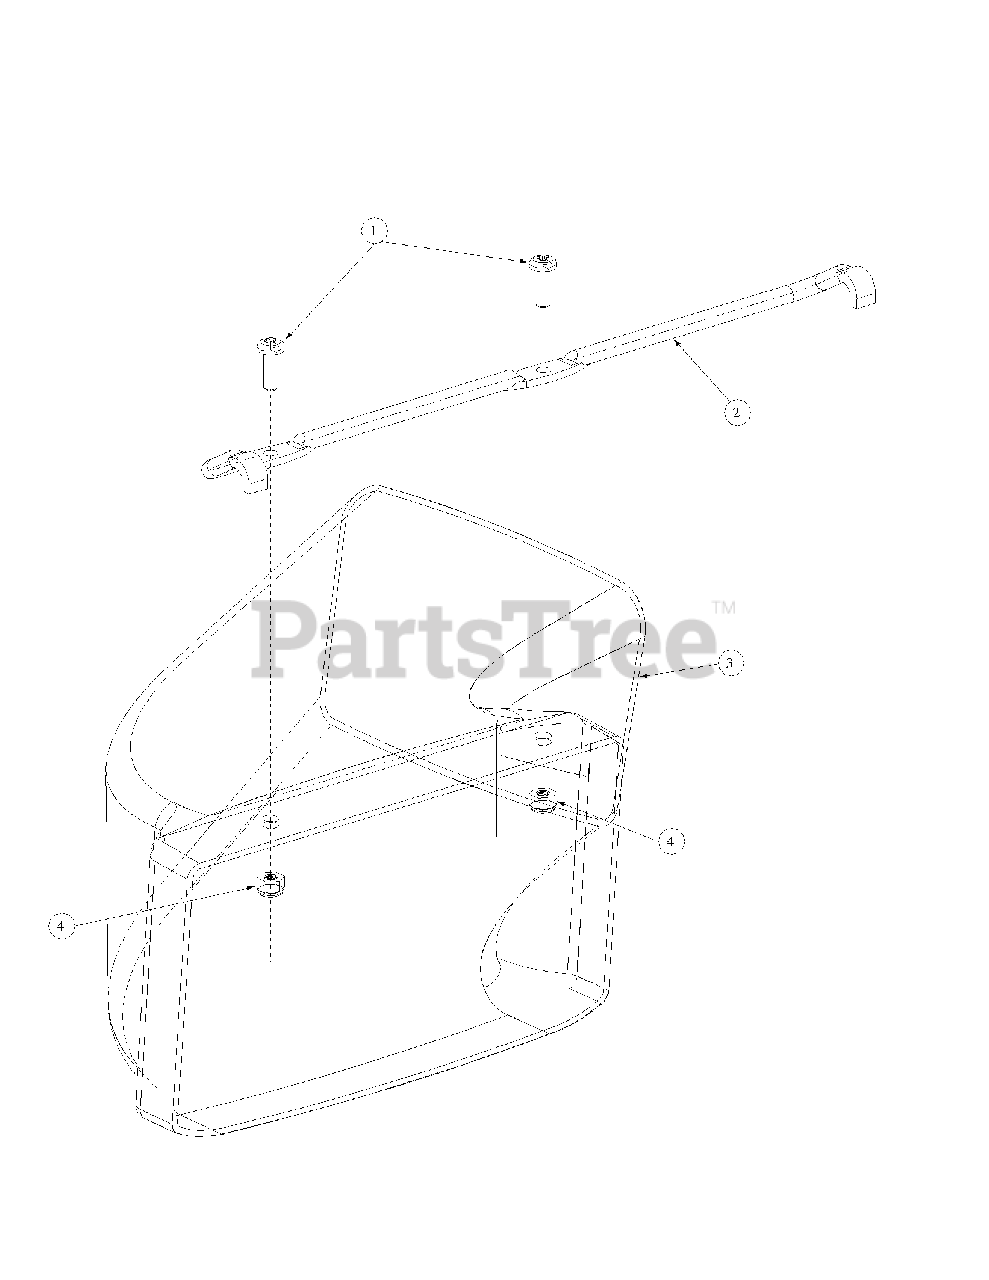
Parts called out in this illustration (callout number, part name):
1	Machine Screw, 1/4-20, .750, PANTRXI
2	21" Side Chute Mounting Rod
3	21" Side Chute Spiral Deck
4	Hex Nut 1/4-20, GRC, Lock
